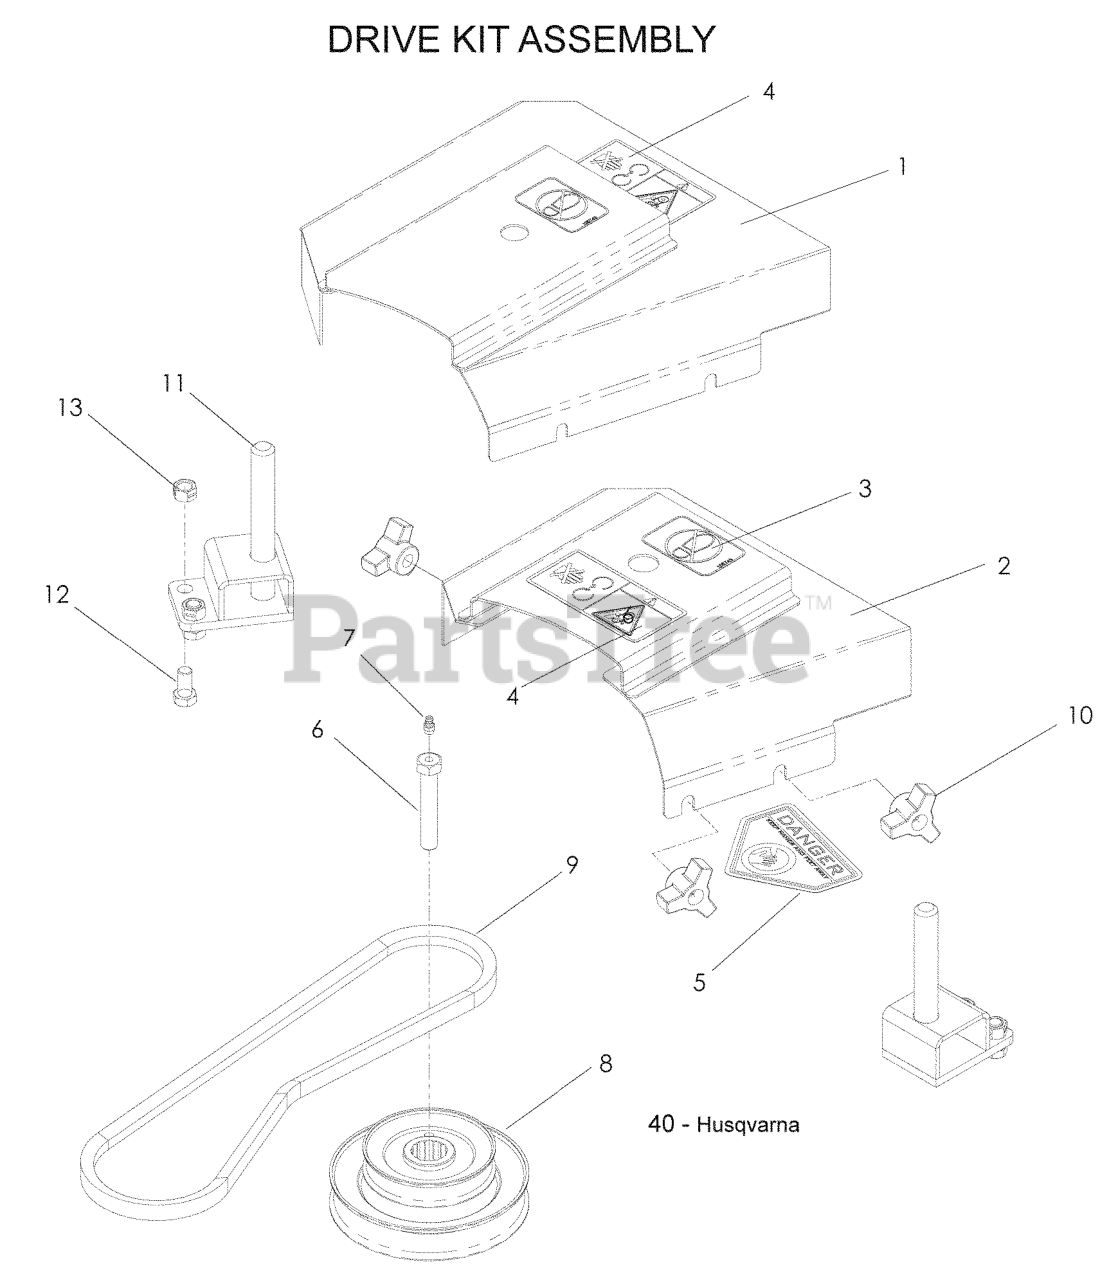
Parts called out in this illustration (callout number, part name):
1	BELT SHIELD W/DECALS, 52
2	BELT SHIELD W/DECALS, 61
3	DECAL, NO STEP
4	DECAL, BELT DRIVE
5	DECAL, CPSC
6	HCS, 7/16-20 X 2 1/2, GR8
7	ZERK
9	V-BELT PUMP DRIVE
10	KNOB, THREE PRONG
11	BLOWER PIN WELDMENT ASM.
12	SCREW 3/8C X 3/4 HEX CAP
13	NUT 3/8C CENTERBLOCK
